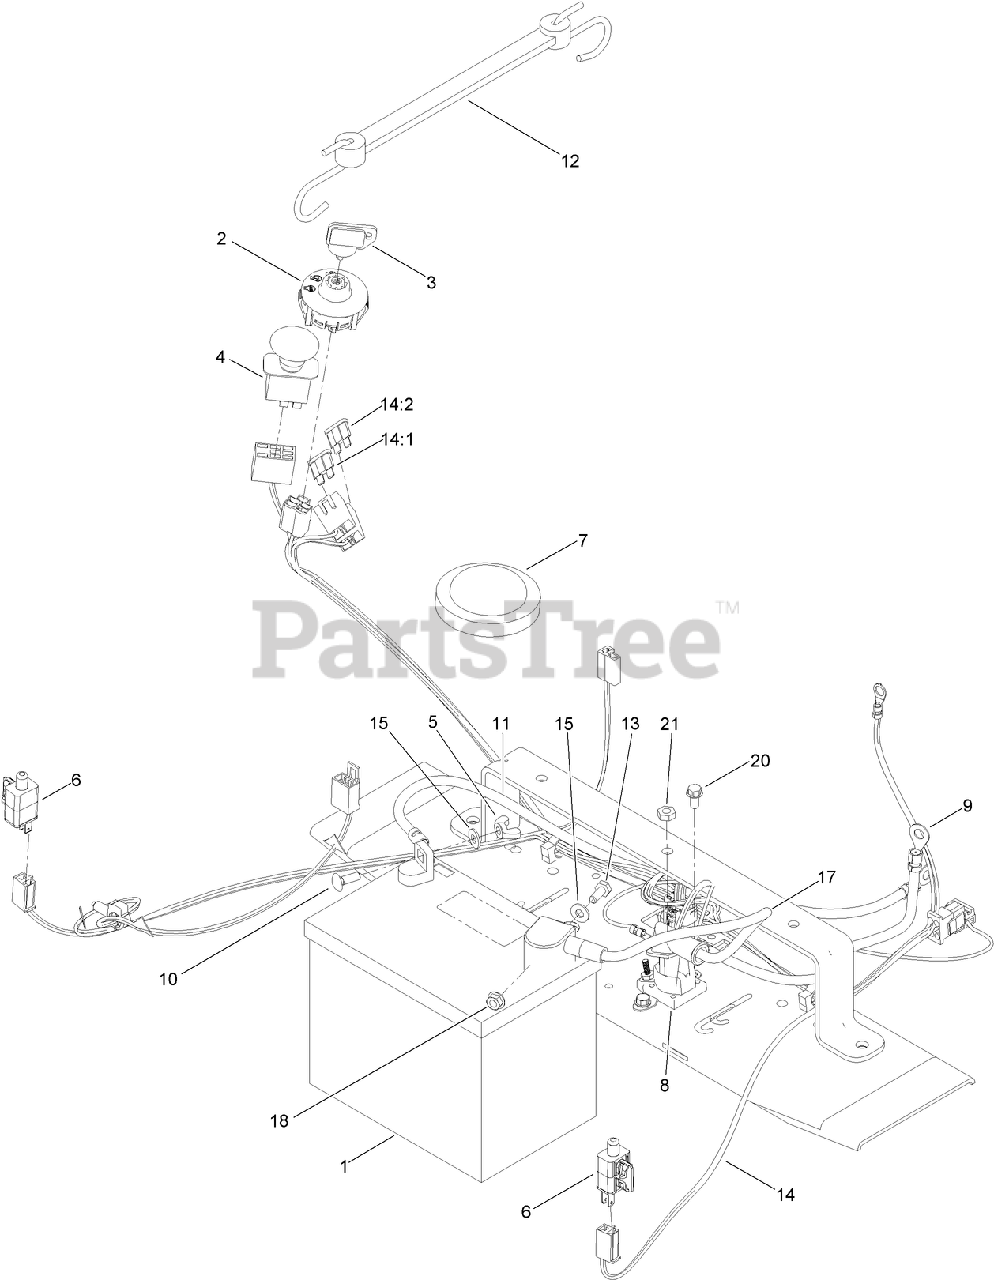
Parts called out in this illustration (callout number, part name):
1	BATTERY
3	KEY-IGNITION
4	SWITCH-PTO
5	NUT-WING
6	SWITCH
7	SWITCH-SEAT
8	SOLENOID
9	CABLE-BATTERY, RED
10	BOLT-CARR
11	CABLE-BATTERY, BLACK
12	HOLDDOWN-BATTERY
13	SCREW-HH
14:1	FUSE-BLADE, 30 AMP
14:2	FUSE-BLADE, 25 AMP
15	WASHER-FLAT
17	CABLE-BATTERY, RED
18	NUT-HF
20	SCREW-HWH
21	NUT-JAM
